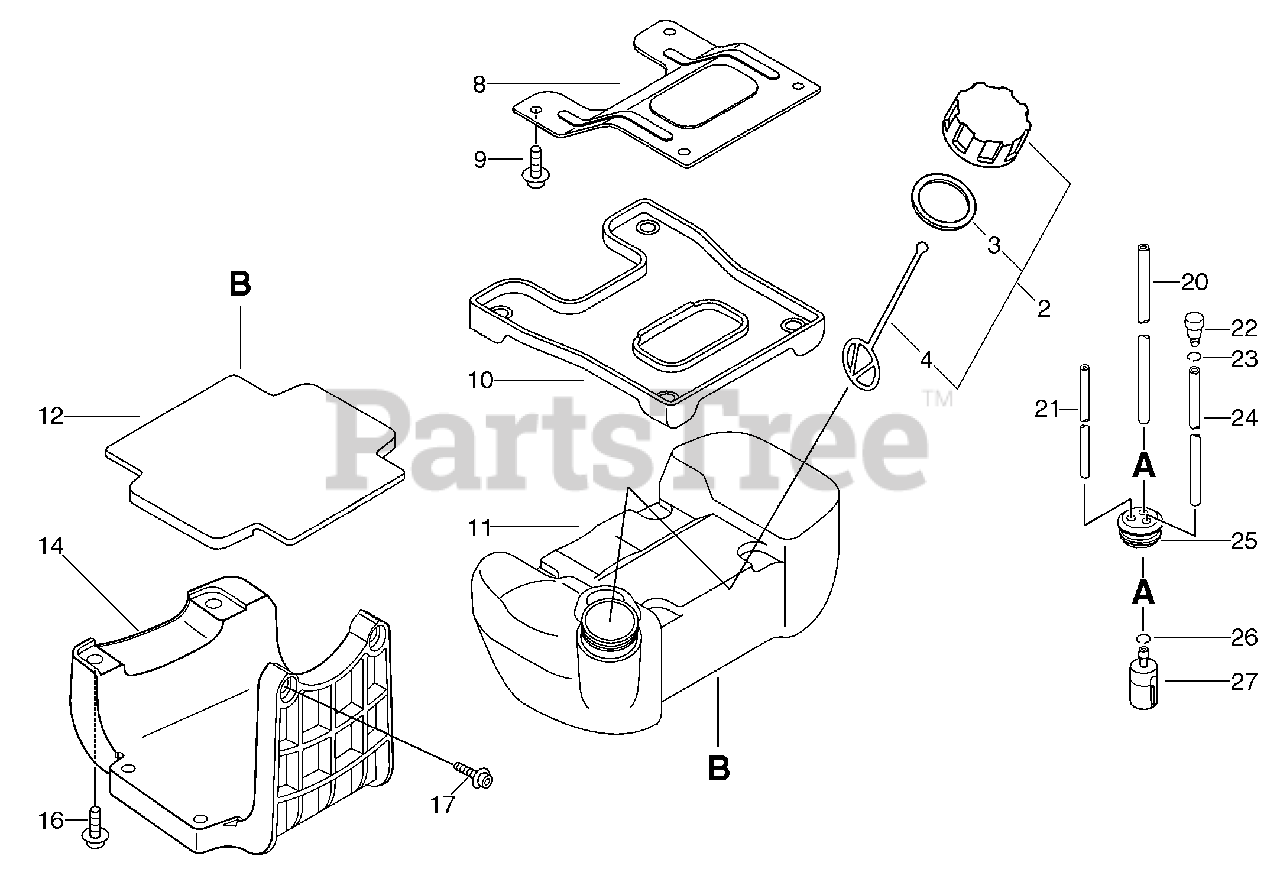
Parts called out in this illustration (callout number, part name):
2	CAP ASSY - ORANGE
3	GASKET, CAP
4	CONNECTOR, CAP
8	BRACKET, FUEL TANK
9	SCREW - 5X12
10	CUSHION, TANK - UPPER
11	TANK, FUEL
12	CUSHION, TANK - LOWER
14	GUARD, FUEL TANK
16	SCREW - 5X20
17	SCREW - 5X25
20	PIPE - 3X6X230 -- BLACK
21	PIPE - 3X6X110 -- CLEAR
22	VENT, FUEL TANK
23	CLIP - 6.5
24	PIPE - 3X6X120 -- BLACK
25	GROMMET
26	CLIP - 6.5
27	FILTER, FUEL
